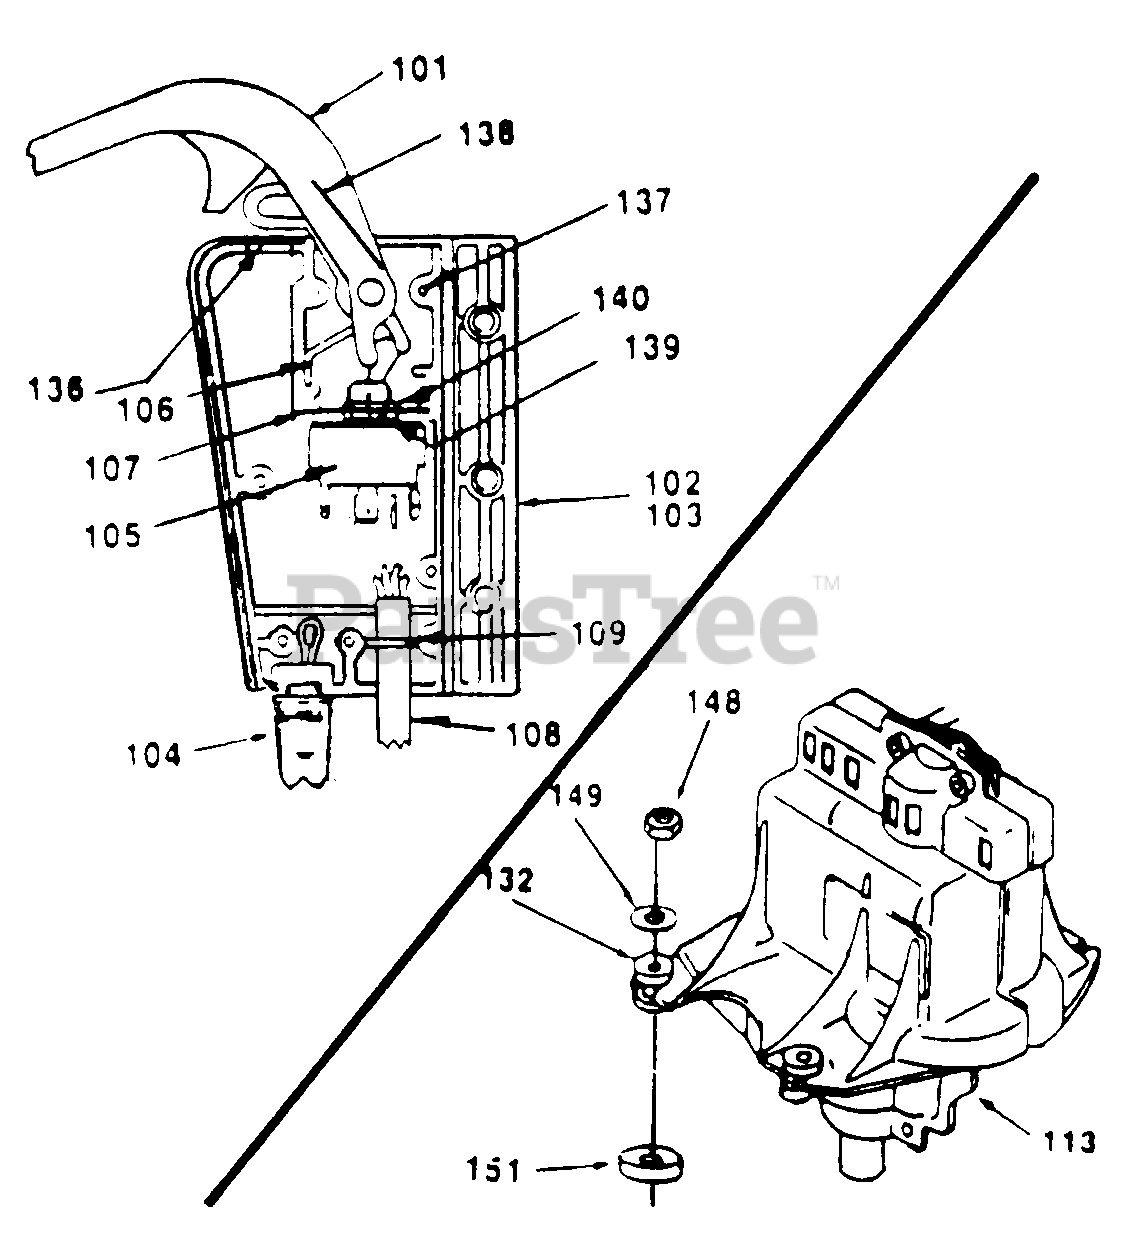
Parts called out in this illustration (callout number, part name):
101	Handle - Switch
102	Housing - Upper Halt
103	Housing - Lower Halt
104	Plug Assembly
105	Switch
106	Spring - Switch Handle
107	Switch Mount Plate
108	Cord Assembly
109	Cord Restraint
113	Motor&SwitchAssembly Complete
132	Insulator - Motor Housing
136	Hole Plug
137	Screw-Switch 80x
138	Interlock Trigger
139	Washer
140	Nut-Switch Mounting
148	Nut 1/4-20 Locking
149	Flat Washer 1/4" I.D.
151	Spacer - Motor Mounting
